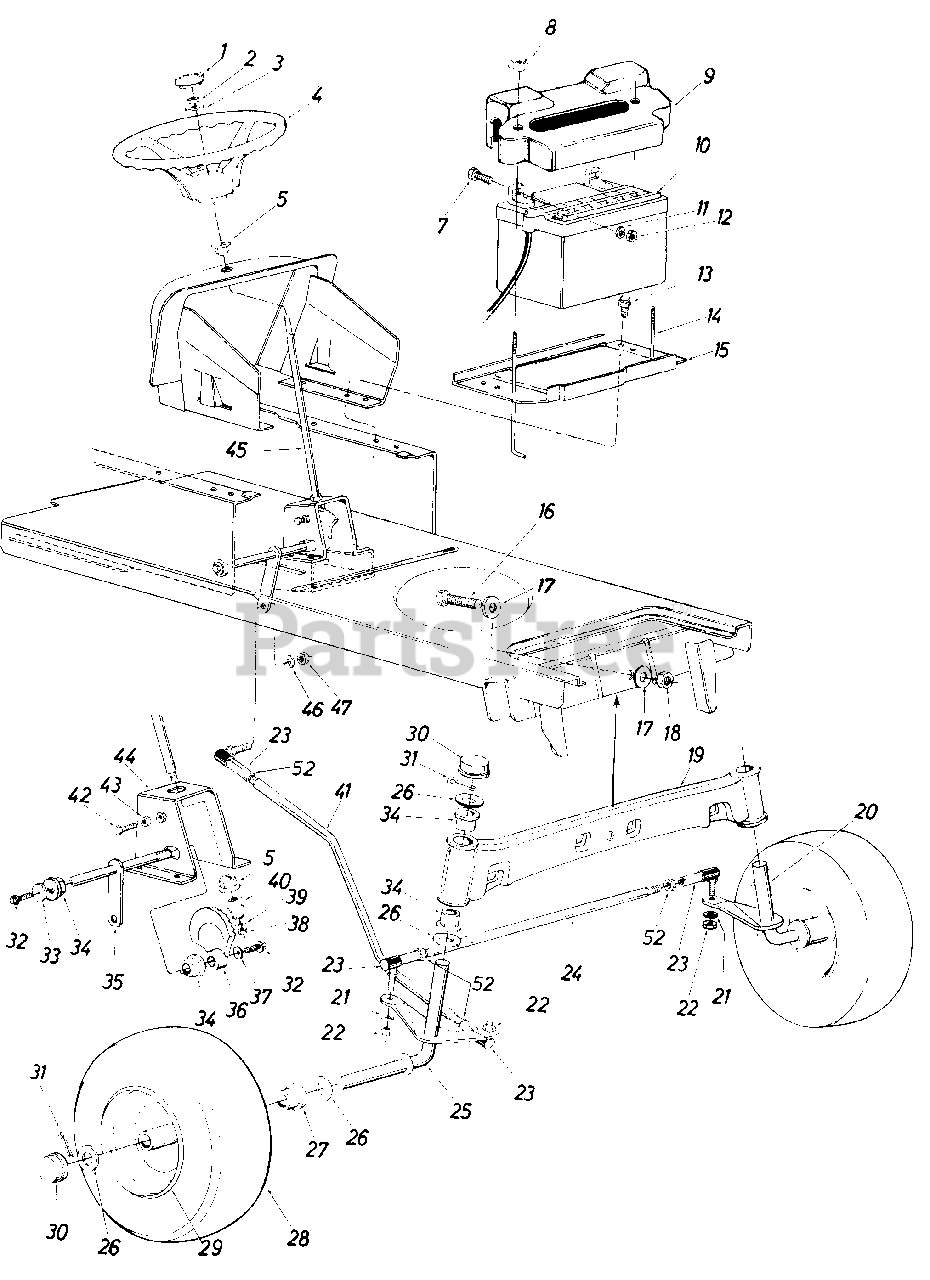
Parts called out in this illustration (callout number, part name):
1	Steering Wheel Cap
2	Hex L-Nut 5/16-18 Thd.
3	Bell-Wash. 5/16" I.D. x .87" O.D. x .060
4	Steering Wheel
5	Plastic Hex Bearing 5/8" I .D.
7	Hex Scr. 1/4-20 x .62" Lg.
8	Wing Nut Plastic 1/4-20 Thd.
9	Battery Cover
10	12-V Battery
11	L-Wash. 1/4" Scr.*
12	Hex Nut 1/4-20 Thd.*
13	Hex Thd. Rolling Scr. 1/4-20 x .50" Lg.
14	Battery Hold Down Rod
15	Battery Plate
16	Hex Scr. 5/8-18 x 2.50" Lg.
17	Flat Wash. .66" I.D. x 2.25" O.D. x .17
18	Hex Cent. L-Nut 5/8-18 Thd.
19	Front Pivot Bar Ass'y.
20	Front Axle Ass'y.-L.H.
21	L-Wash. 3/8" Scr.
22	Hex Nut 3/8-24 Thd.
23	Ball Joint Ass'y.
24	Tie Rod
25	Front Axle Ass'y.-R.H.
26	Fl-Wash. .780 I.D. x 1.59 O.D.
27	Flange Bearing
28	Front Wheel Ass'y. Comp.
29	Front Wheel Rim Only
30	Dust Cover
31	Cotter Pin 5132" Dia. x 1.00" Lg.*
32	Hex Scr. 3/8-24 x .75" Lg. Grade 5
33	Fl-Wash. 3/8 I.D. x 1.25 O.D. x .090
34	Flange Double "D" Brg. .753 I.D.
35	Steering Arm Shaft Ass'y.
36	Side Gear-Steering
37	Bell-Wash. 3/8" I.D.
38	Hex Cent. L-Nut 5/16-24 Thd.
39	Fl-Wash. 5/16" I.D. x .62 O.D. x .059
40	Pinion Gear-Steering
41	Drag Link
42	Hex Nylon Scr. 3/8-16 x 1.25" Lg.
43	Hex Nut 3/8-16 Thd.*
44	Steering Gear Sup. Ass'y.
45	Steering Shaft
46	L-Wash. 3/8" Scr.
47	Hex Nut 3/8-24 Thd.*
52	Hex Jam Nut 3/8-24 Thd.
